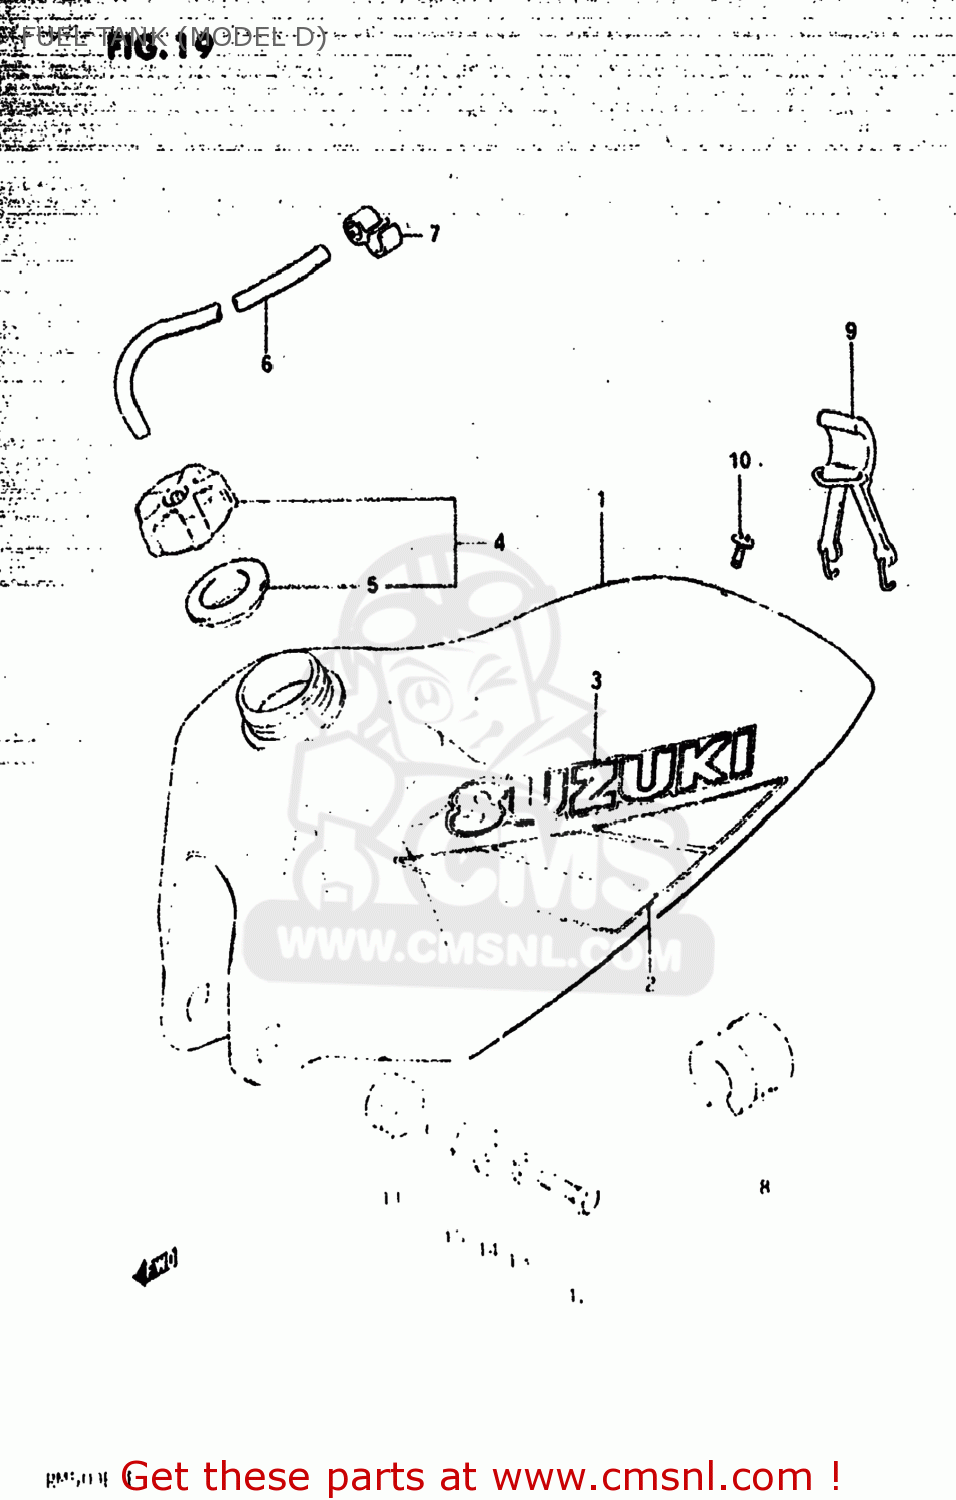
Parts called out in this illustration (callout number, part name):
1	TANK ASSEMBLY,FUEL
2	TAPE SET,FUEL TANK
3	EMBLEM
4	CAP SET,FUEL TANK
5	GASKET,FUEL TANK CAP (NAS)
6	HOSE
7	CLAMP,BREATHER HOSE
8	CUSHION,FUEL TANK UPR
9	BAND,FUEL TANK,REAR
10	SCREW (6X15)
11	CUSHION
12	BOLT (8X30)
13	LOCK WASHER
14	WASHER
15	SPACER (8.8X12X13.5)
